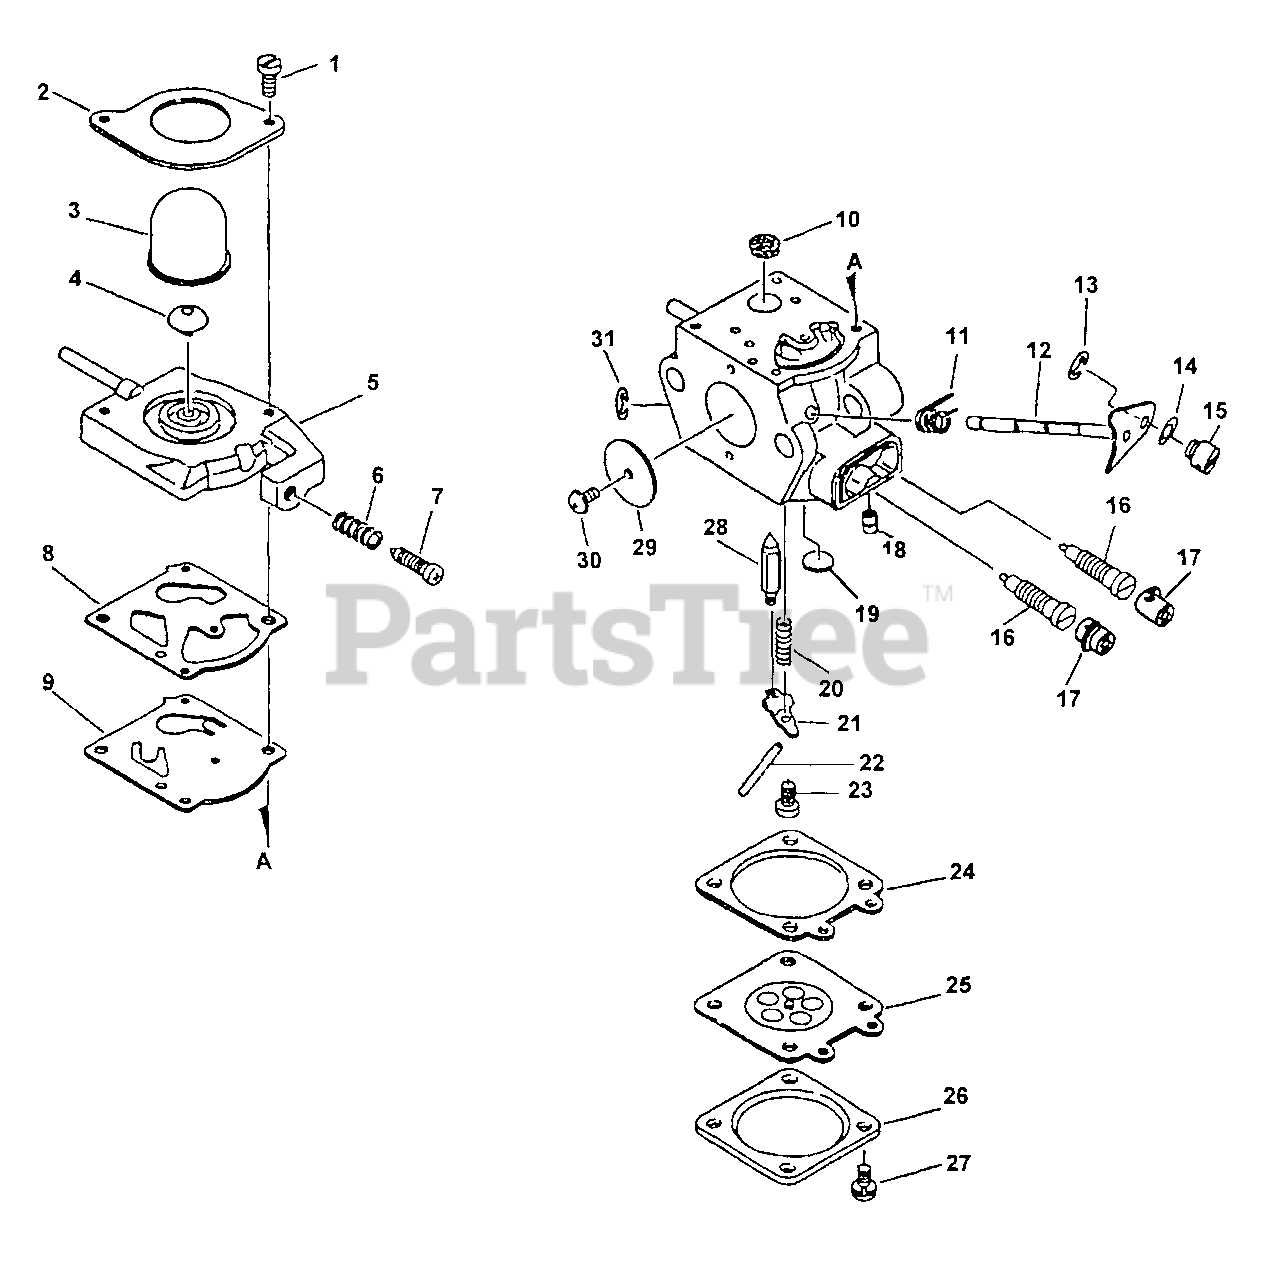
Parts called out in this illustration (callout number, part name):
1	SCREW, PUMP COVER
2	RETAINER, PURGE BULB
3	BULB, PURGE
4	VALVE, CHECK
5	BASE, PURGE
6	SPRING, IDLE ADJUST
7	SCREW, IDLE ADJUST
8	GASKET, PURGE
9	DIAPHRAGM, PURGE
10	STRAINER
11	SPRING, THROTTLE RETURN
12	SHAFT, THROTTLE
13	RING, RETAINING
16	NEEDLE - MIXTURE
17	CAP, LIMITER
18	NOZZLE, CHECK VALVE
19	PLUG, WELCH
20	SPRING, METERING LEVER
21	LEVER, METERING
22	PIN, METERING LEVER
23	SCREW, METERING LEVER PIN
24	GASKET, METERING
25	DIAPHRAGM, METERING
26	COVER, METERING
27	SCREW
28	VALVE, INLET NEEDLE
29	VALVE, THROTTLE
31	RING, RETAINING
